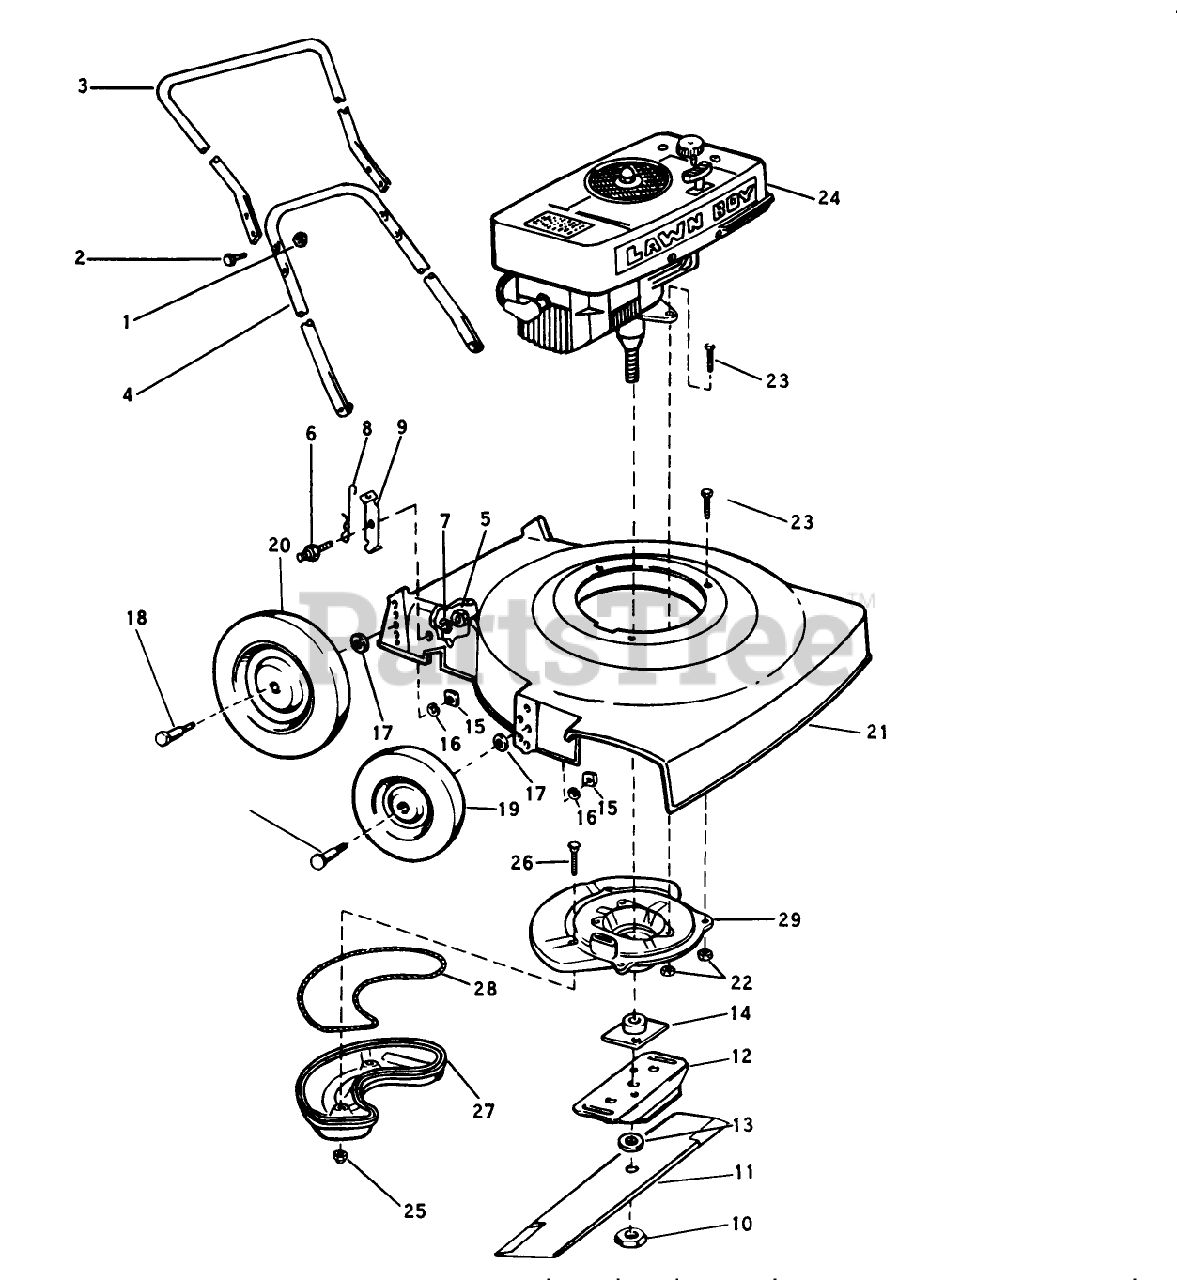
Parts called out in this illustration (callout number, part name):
7	Lockwasher
10	NUT-BLADE
14	PLATE AND COLLAR ASM
16	WASHER, LOCK
17	WASHER WROUGHT
25	LOCKNUT E
